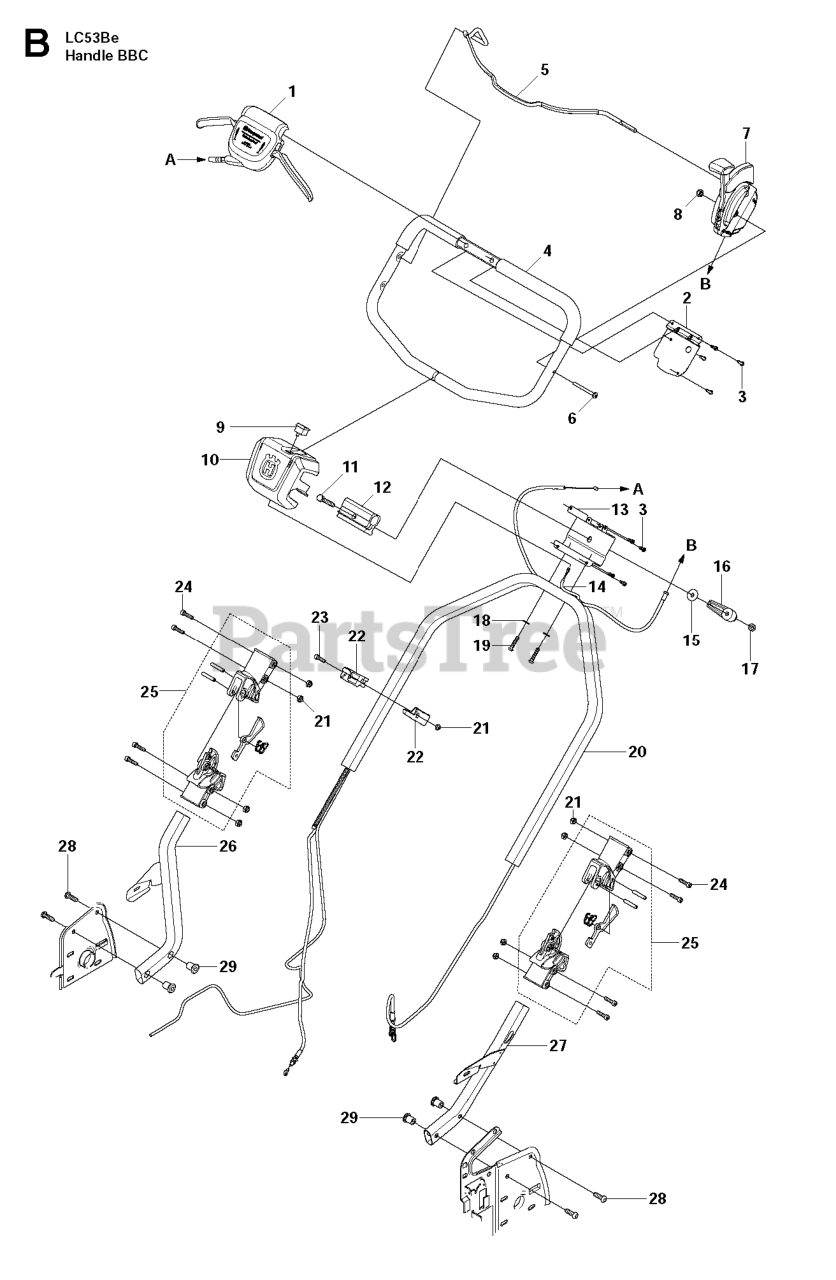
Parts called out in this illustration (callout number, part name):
1	GASKET
3	RP_BOLT
4	MUFFLER ASSY
5	SPARK ARRESTOR SCREEN
6	EXHAUST DUCT
